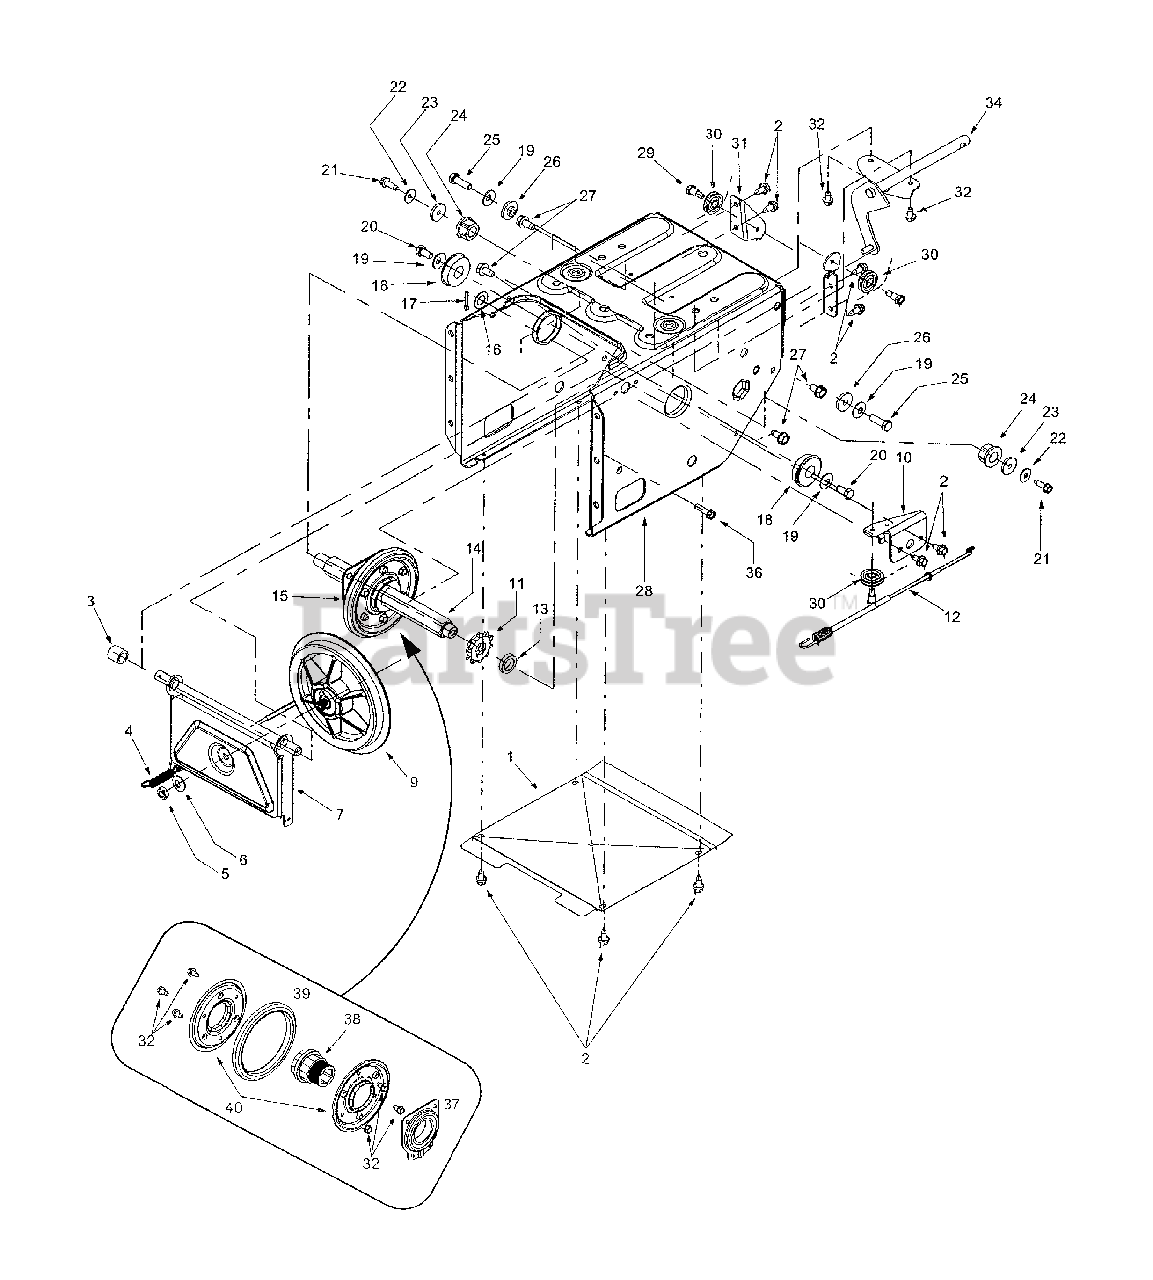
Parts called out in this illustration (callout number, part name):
3	Spacer, .508 ID x .75 OD x .68
4	Ext. Spring
5	Jam Nut, 3/8-24
6	Bell Washer, .401 x .87 x .063
9	Friction Disc
12	Auger Cable, 44.75"
13	Spacer, .675 ID x 1 OD x .23
14	Hex Track Shaft
15	Friction Wheel Assembly
16	Flat Washer, .536 ID x .93 OD x .05
17	Cotter Pin
18	Ball Bearing
19	Bell Washer, .34 ID x .872 OD
20	Hex Cap Screw, 5/16-18 x .625
21	Tap Screw, 1/4-20 x .75
22	Bell Washer, .265 x .75 x .062
23	Flat Washer, 1/4 ID x .93 OD x .12
24	Hex Flange Bearing
25	Hex Cap Screw, 5/16-18 x 1
26	Shoulder Spacer
27	Tap Screw, 5/16-18 x .625
29	Spacer
30	Cable Roller
37	Friction Wheel Bearing
38	Friction Wheel Hub
39	Friction Wheel Rubber
40	Friction Plate
